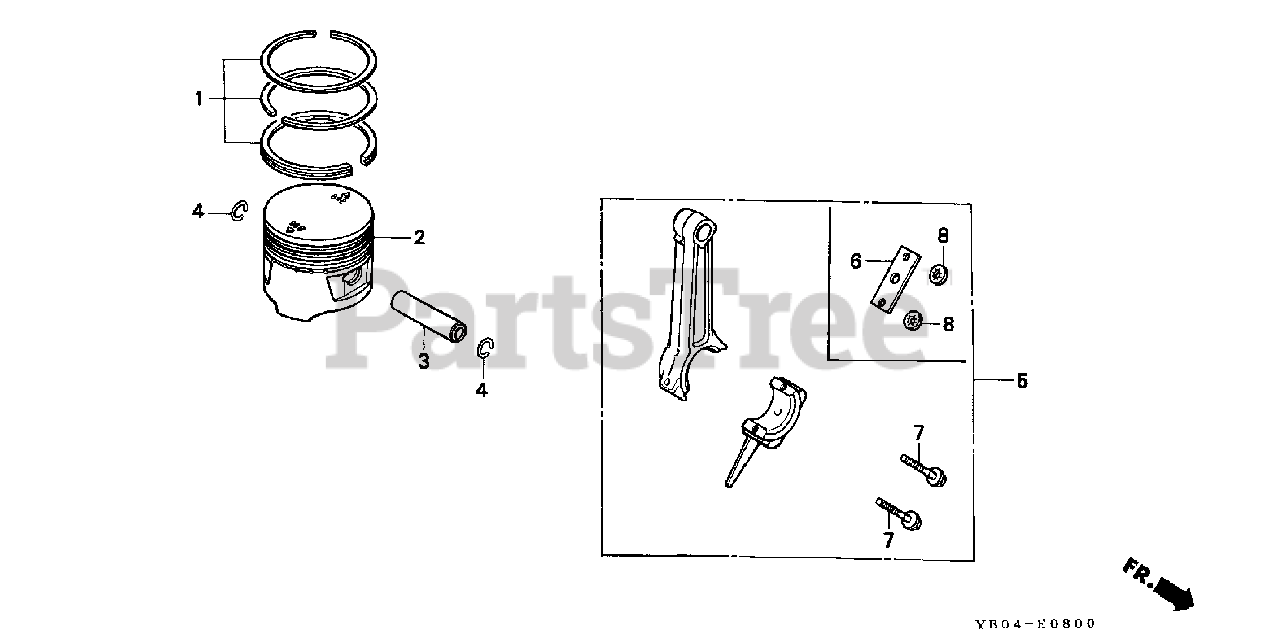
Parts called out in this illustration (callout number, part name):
1	RING SET, PISTON (STD)
1	RING SET, PISTON (OS 0.25)
1	RING SET, PISTON (OS 0.50)
1	RING SET, PISTON (0.75)
2	PISTON
2	PISTON (STD)
2	PISTON (OS 0.25)
2	PISTON (OS 0.50)
2	PISTON (0.75)
3	PIN, PISTON
4	CLIP, PISTON PIN (10MM)
5	ROD ASSY., CONNECTING (STD)
5	ROD ASSY., CONNECTING (US) Use from Engine SN 1443596.
5	ROD ASSY., CONNECTING
5	ROD ASSY., CONNECTING Use up to Engine SN 1443595.
6	WASHER, CONNECTING ROD (NOT AVAILABLE)
7	BOLT, CONNECTING ROD
8	WASHER, LOCK
